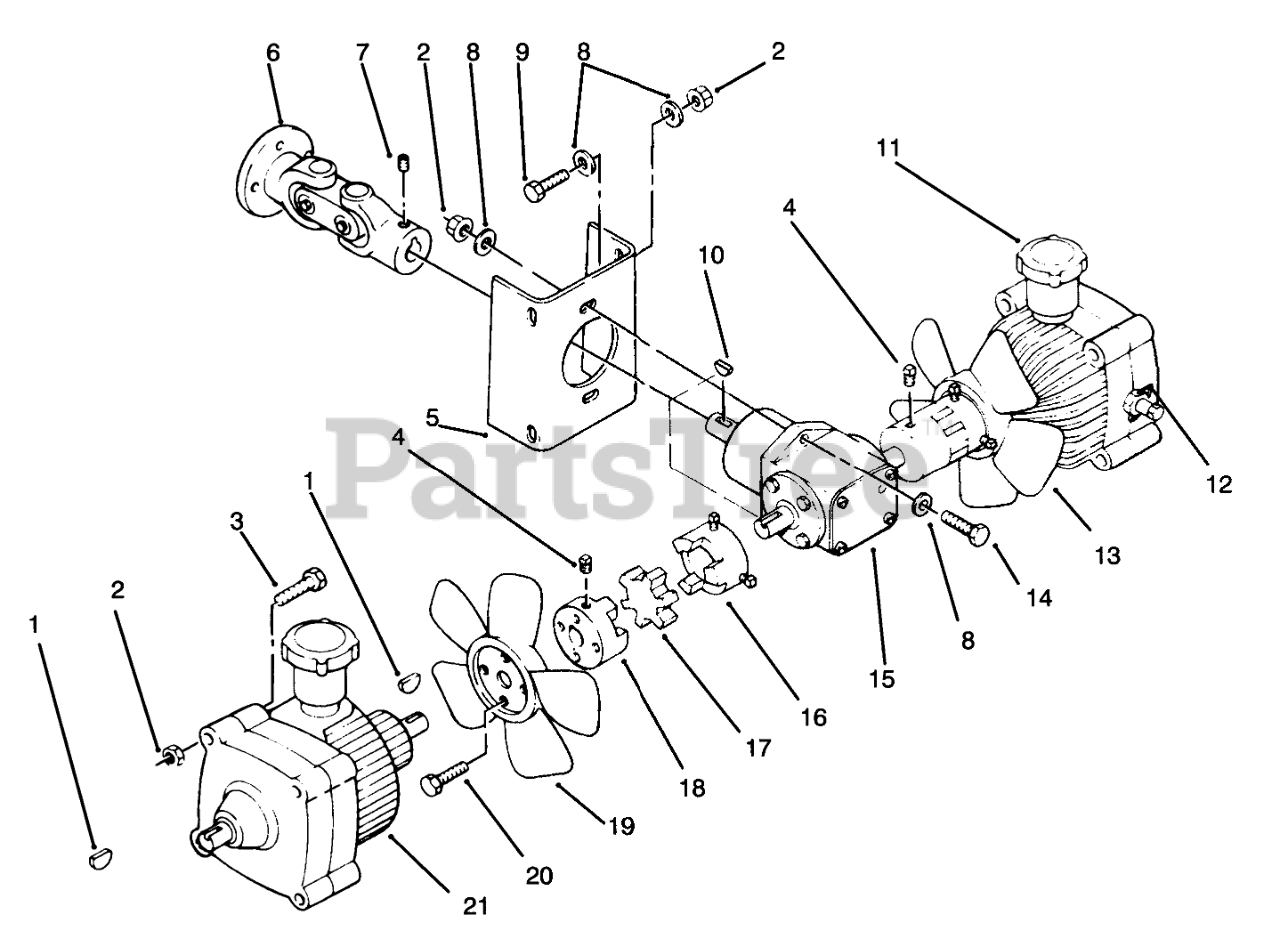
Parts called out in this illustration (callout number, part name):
1	KEY-HIPRO
2	NUT-LOCK, NI
3	SCREW-HH
4	1/2X1 CUP PT SETSCREW
5	BRACKET-GEAR BOX B
6	U-JOINT ASSY W/FLANGE
7	SCREW-SET
8	WASHER-FLAT
9	SCREW-HH
10	KEY-HI-PRO
11	TRANS-HYDRO CW
12	CLIP-DUMP VALVE
13	BLADE-FAN L.H.
14	SCREW-HH
15	GEAR BOX-T
16	COUPLING-KEYED
17	SPIDER-COUPLING
18	COUPLING-KEYED
19	BLADE-FAN R.H.
20	SCREW-TAPTITE
21	TRANS-HYDRO CCW.
